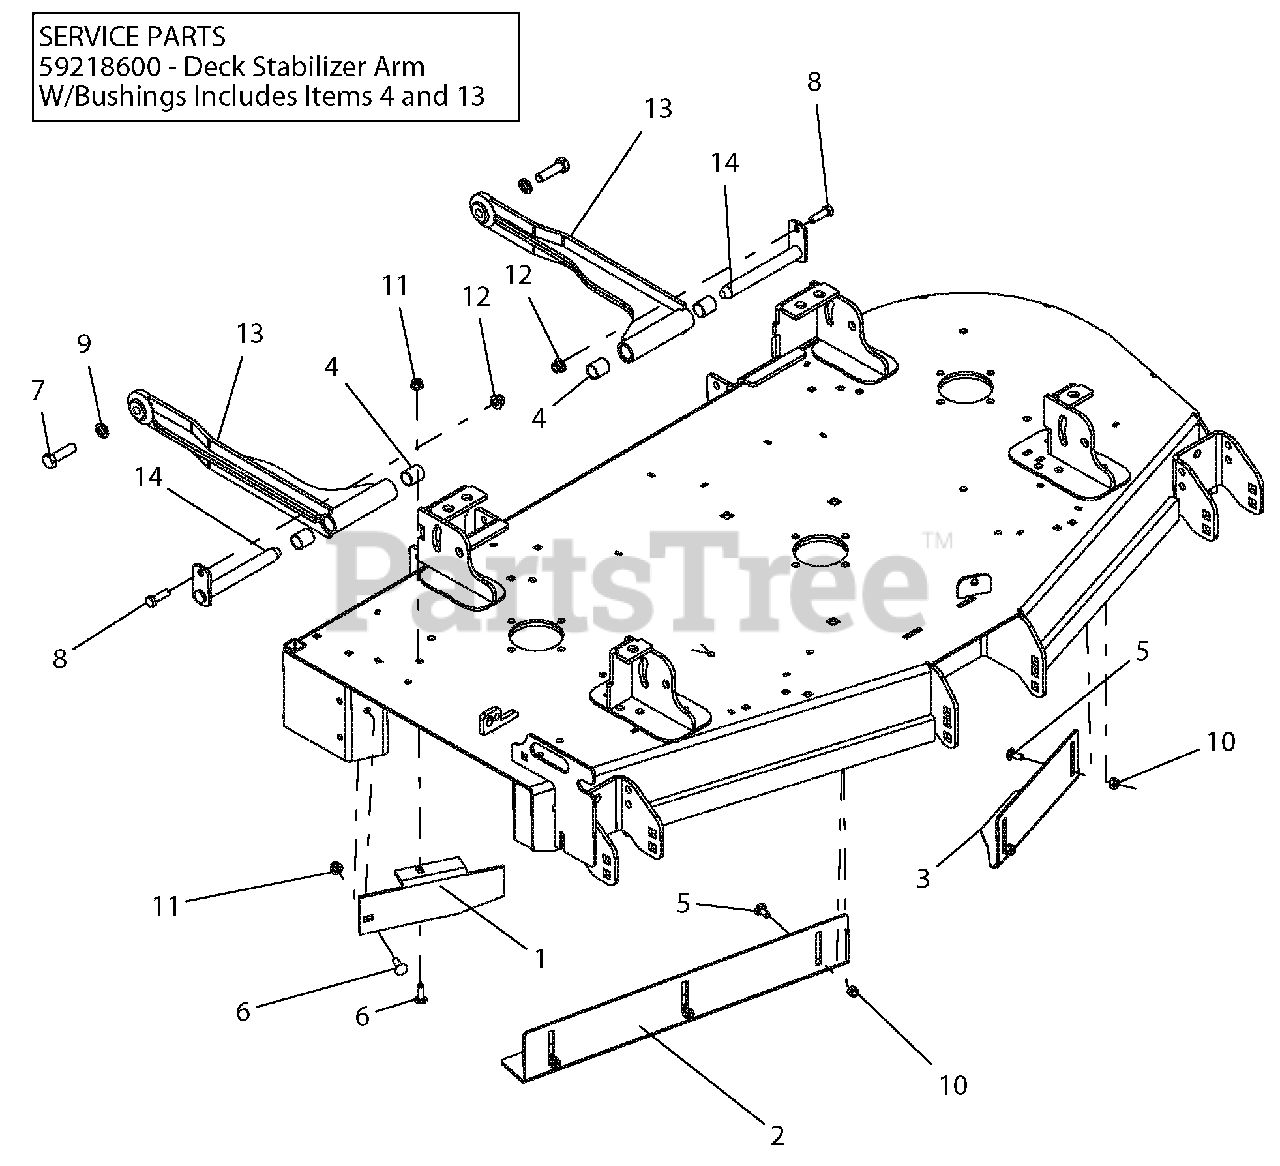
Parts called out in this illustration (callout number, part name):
1	BAFFLE, 52" DISCHARGE-RED
2	BAFFLE, 52" RH VACUUM-BLACK
3	BAFFLE, 52" LH VACUUM-BLACK
4	BRG, .75 X .875 X 1.00
5	BLT-RDHDSQNK .31-18X.75 G5 YWZC
6	BLT-RDHDSQSHNK .31-18X1.00 G5 Y
7	BLT-HEX .50-13X1.75 GR5 YWZC EP80
8	BLT-HEX .38-16X1.25 GR5 YWZC
9	WSHR-LK .50X.125 REG YWZC
10	NUT-LK-NYL .312-18 YWZC
11	NUT-LK-NYL-FLG .31-18 YWZC
12	NUT-LK-NYL-FLG .38-16 YWZC
13	WMT, DECK STABILIZER ARM-BLACK
14	WLDMT, MOWER MTG. PIN
